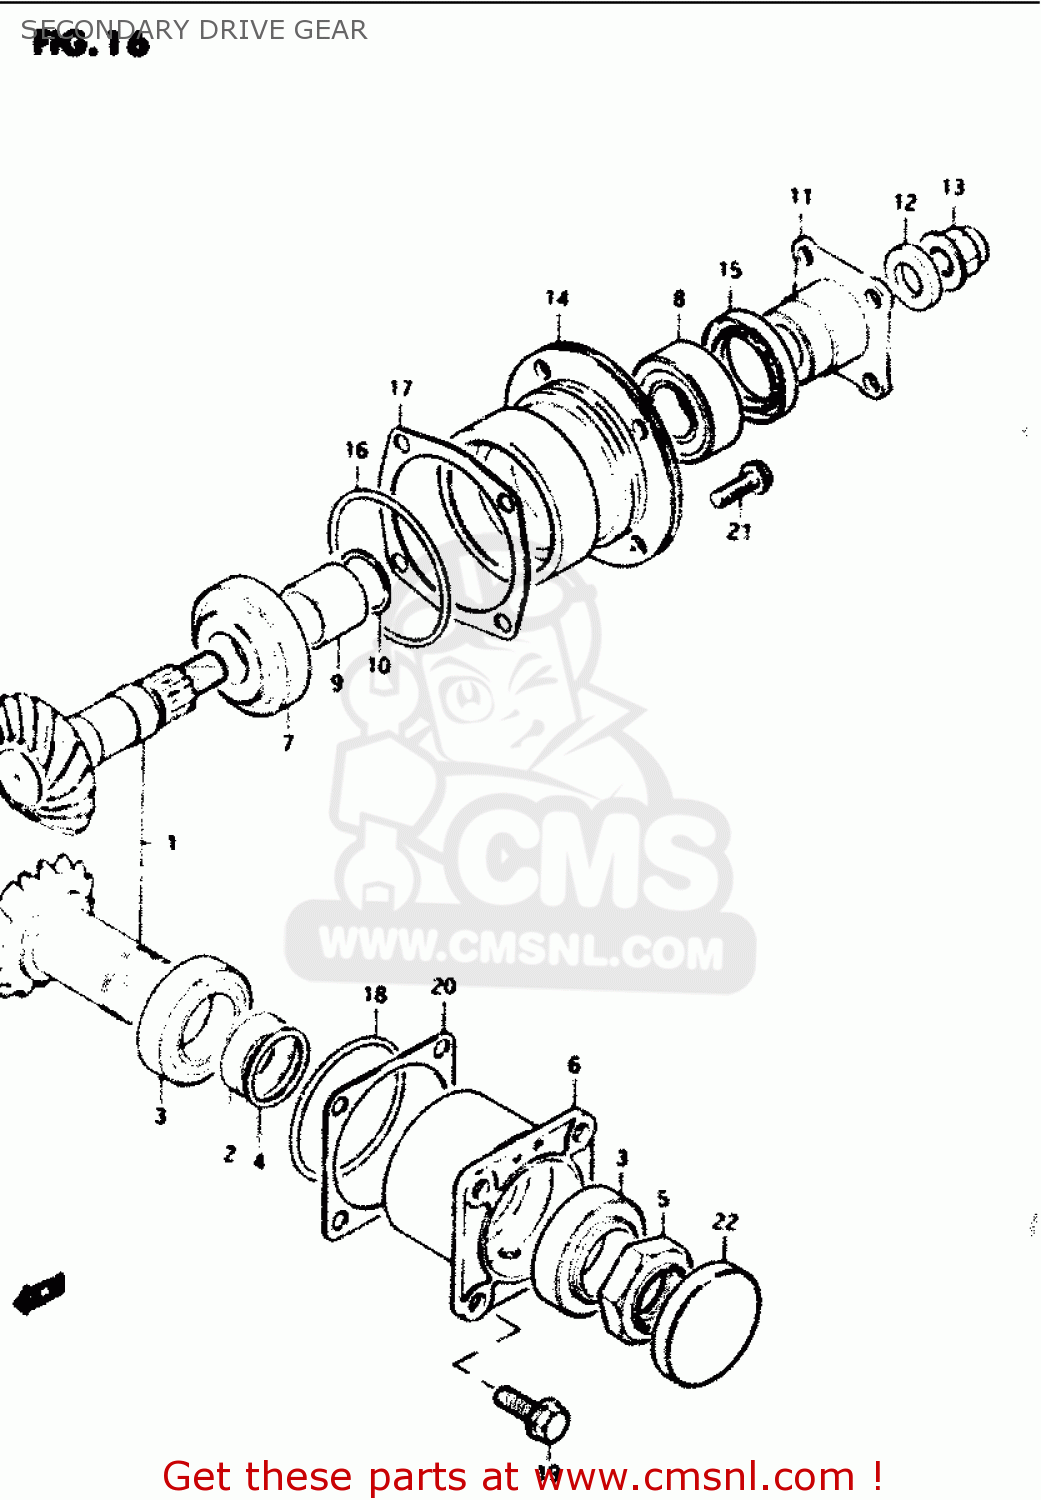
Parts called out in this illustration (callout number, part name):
1	SECONDARY GEAR SET
2	SPACER (32.4X38X12.5)
3	BEARING(32X58X17)
4	SHIM(32X38X2)
5	NUT
6	HOUSING,SECONDARY DRIVE
7	TAPER,ROLLER BEARING
8	BEARING
9	SPACER (25.2X30X40)
10	SHIM (25X30X2
11	FLANGE,UNIVERSAL JOINT
12	WASHER(14X29X4)
13	NUT
14	HOUSING,SECONDARY DRIVE
15	SEAL,OIL(35X52X9)
16	O RING(D:3.1,ID:69.4)
17	SHIM,DRIVEN GEAR HOUSING
18	O RING(D:2.4,ID:62.6)
19	BOLT
20	SHIM,SECONDARY DRIVE
21	BOLT
22	PLUG
